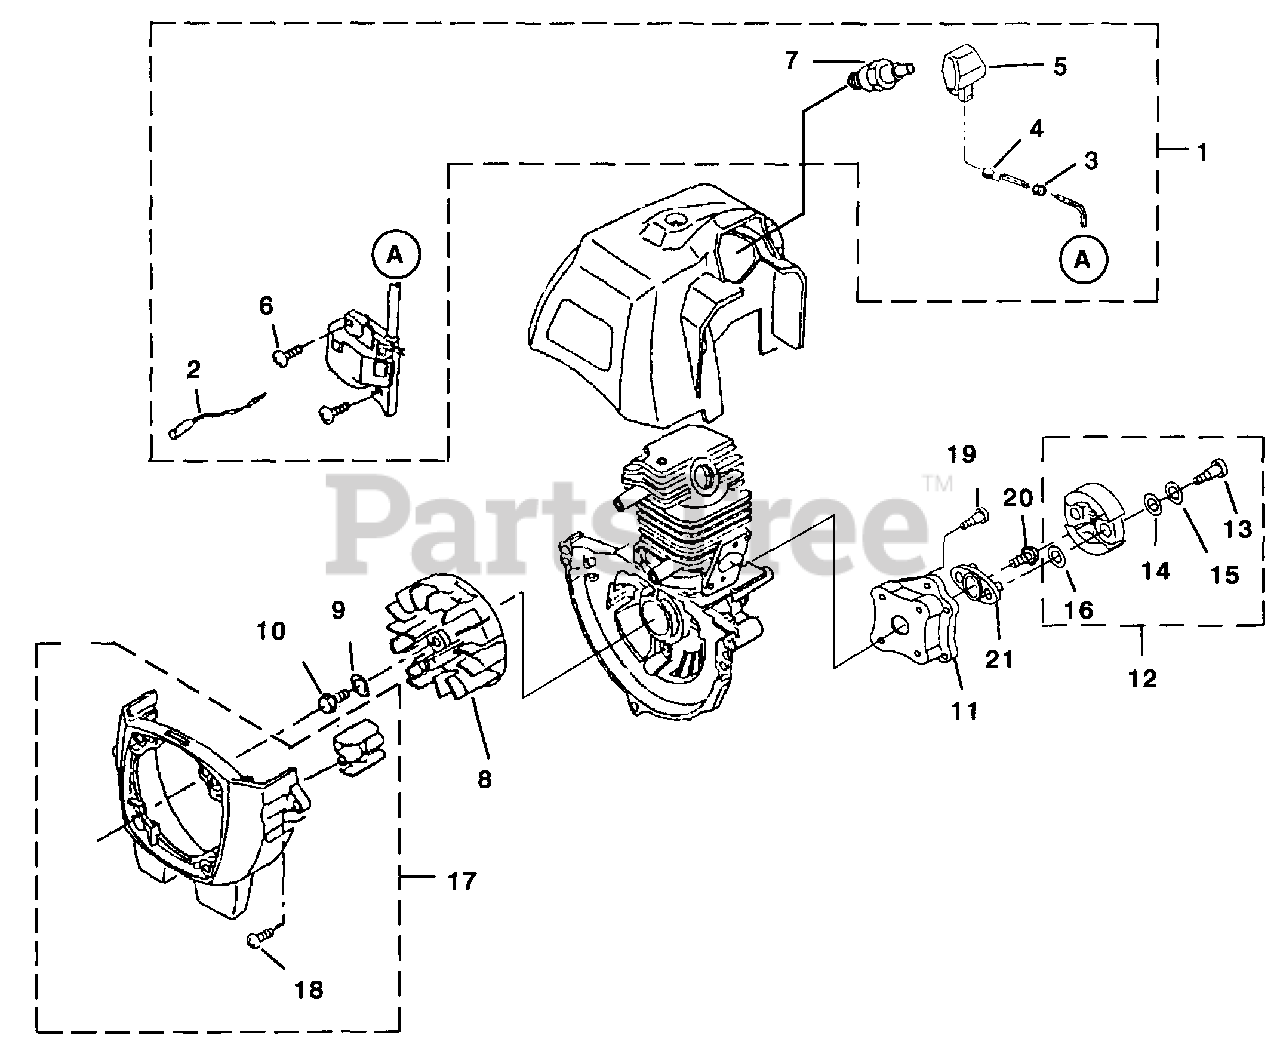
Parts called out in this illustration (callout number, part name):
1	IGNITION KIT
2	WIRE-Ground
4	SPRING-Plug Cap
5	CAP-Plug
6	SCREW (M5 x 20)
7	SPARK PLUG
10	BOLT ASSEMBLY (M6 x 16)
11	ENGINE BASE
12	CLUTCH ASSEMBLY
13	BOLT-Clutch
17	BLOWER HOUSING ASSEMBLY
18	SCREW ASSEMBLY
19	SCREW ASSEMBLY (M5 x W SW)
20	BOLT ASSEMBLY (M5 x 16)
21	HOLDER-Clutch
